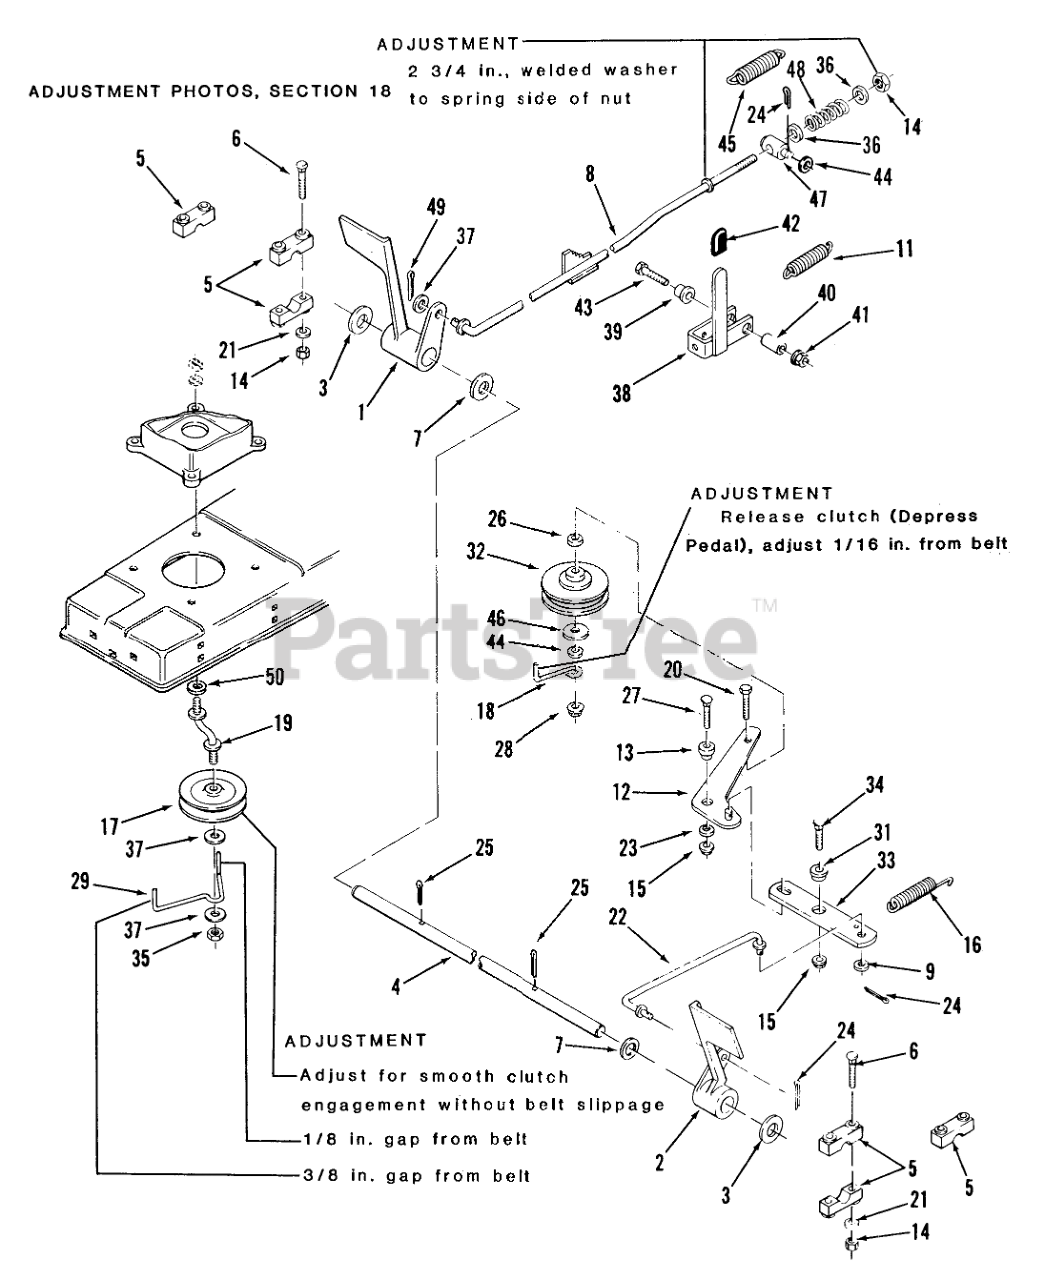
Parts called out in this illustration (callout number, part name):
1	PEDAL-BRAKE R
2	PEDAL CLUTCH R
3	WASHER-SPECIAL
4	SHAFT-PEDAL
5	BLOCK PIVOT
6	Washer
7	Washer
8	ASSY-BRAKE ROD
8	Brake Rod 208-3, 211-3 Only
9	WASHER 5/16 SAE
11	SPRING-EXTENSION
12	IDLER ARM ASSY R
13	SPACER-IDLER ARM
14	Nut
15	LOCKNUT-FLANGE
16	SPRING
17	PULLEY-IDLER STATION
18	RETAINER-BELT
20	Bolt
21	WASHER 5/16 SAE
22	ROD-CLUTCH R
23	Washer
24	Pop Rivet
26	SPACER
27	Carriage Bolt
28	LOCKNUT-FLANGE
29	RETAINER-BELT
31	SPACER
32	IDLER PULLEY
33	BAR-CLUTCH
34	Bolt
35	Nut
36	Collar
37	Washer
38	PAWL-HANDLE ASSY
39	SPACER
40	SPACER
41	LOCKNUT-FLANGE
42	GRIP
43	Bolt
44	Washer
45	SPRING-EXTENSION
46	WASHER
47	TRUNNION-LIFT
48	SPRING FRICTION
49	Cotter Pin
50	Washer-Lock
